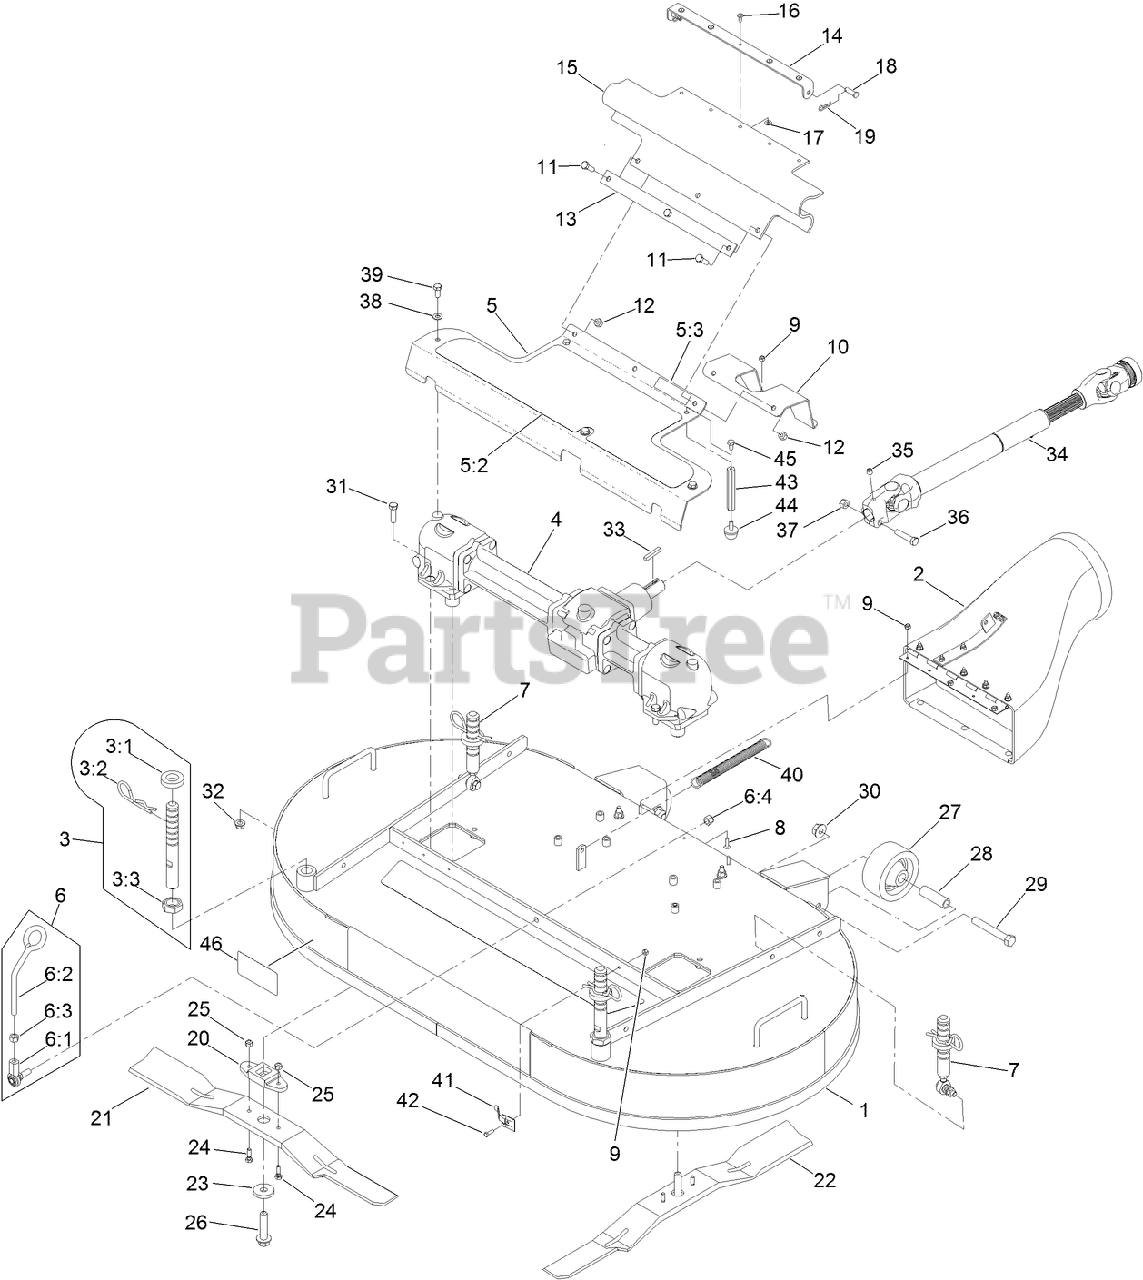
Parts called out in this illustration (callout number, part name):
1	DECK DECAL and BAFFLE ASM
2	DISCHARGE TUBE ASM
3	FRONT DECK HEIGHT ADJUST ASM
3:1	SPACER-DECK SUPPORT
3:2	PIN-CUT HEIGHT
3:3	NUT-JAM
4	GEAR BOX ASM
5	GEARBOX COVER ASM
5:2	PAD-ANTI SKID
5:3	DECAL-DANGER
6	DECK LATCH ASM
6:1	BALLJOINT-RH
6:2	LATCH-DECK
6:3	NUT-HEX
6:4	NUT-LOCK
7	REAR DECK HEIGHT ADJUST ASM
8	SCREW-HEAD, TRUSS
9	NUT-LOCK, NI
10	GUARD-DRIVE SHAFT
11	SCREW-HH
12	NUT-LOCK, NI
13	STRAP-DRIVE, LINE COVER
14	BRACKET-GUARD, PTO
15	GUARD-PTO
16	RIVET-BLIND
17	WASHER-FLAT
18	PIN-CLEVIS
19	PIN-COTTER
20	DRIVER-BLADE
21	BLADE-25IN, RH
22	BLADE-25IN, LH
23	WASHER
24	BOLT-SHEAR
25	NUT-LOCK, NI
26	BOLT-BLADE
27	ROLLER-DECK
28	SPACER-ROLLER
29	SCREW-HH
30	NUT-HHF
31	SCREW-HH
32	NUT-HHF, WHIZ
33	KEY-SQUARE
34	DRIVE SHAFT ASM
35	SCREW-SET, HSH
36	SCREW-HH
37	NUT-LOCK, NI
38	WASHER-PLAIN
39	SCREW-HH
40	SPRING-EXTENSION
41	CLIP-DECK, HOLD UP ROD
43	STAND-OFF
44	BUMPER
45	SCREW-HH
